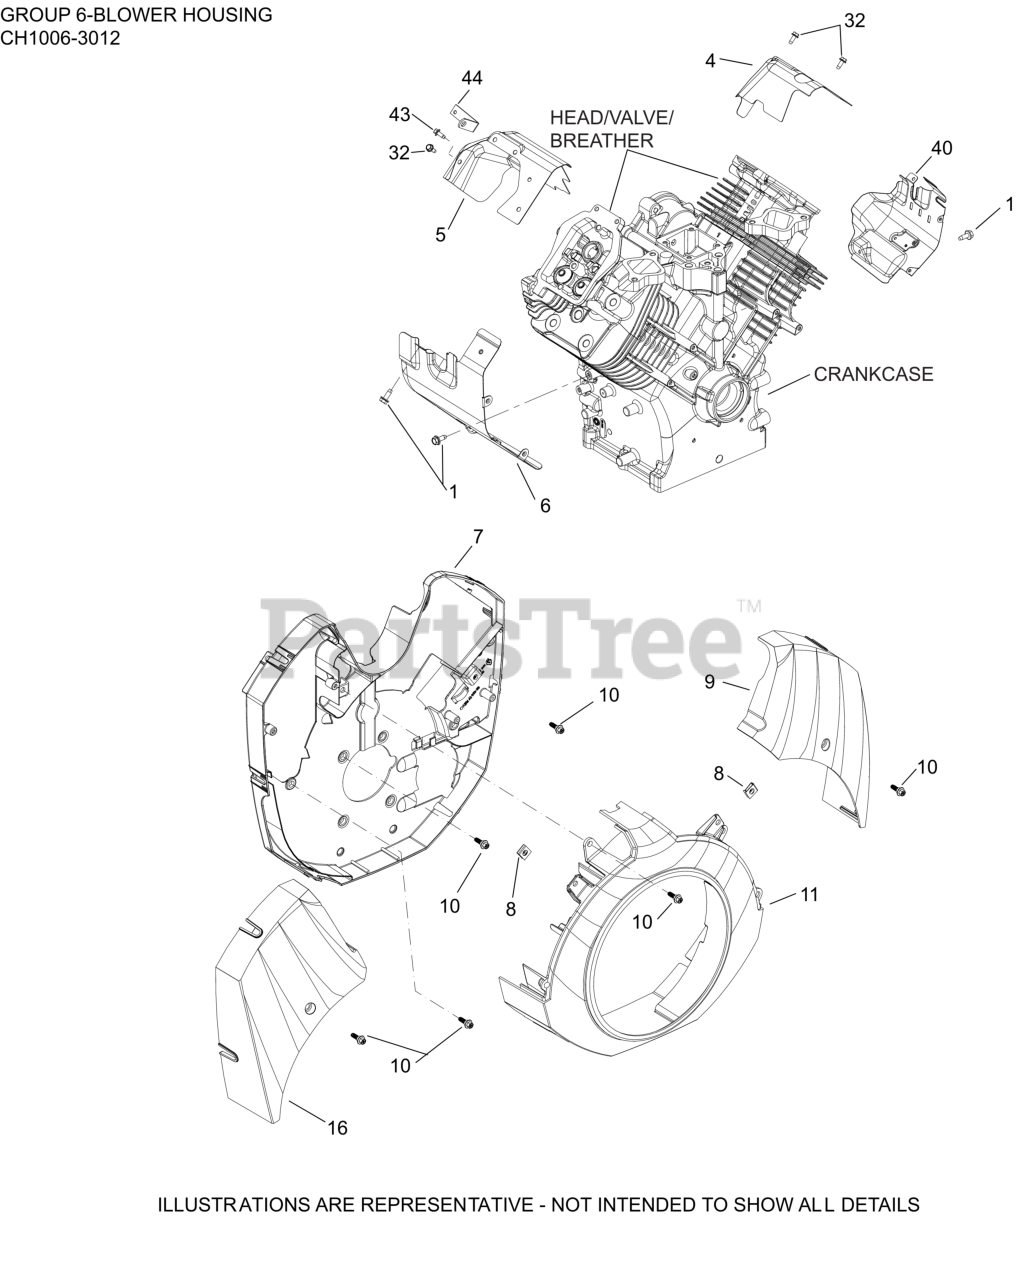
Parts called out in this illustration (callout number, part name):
1	SCREW, THREAD FORMING
4	BAFFLE, VALLEY #1 CYLINDER
5	BAFFLE, VALLEY #2 CYL-USE 62 063 40-S
6	BAFFLE, BARREL (#2 CYL)
7	SHROUD AND CLIP ASSEMBLY
8	CLIP, BAFFLE MOUNTING
9	SHROUD, #1 CYLINDER
10	SCREW, SHD THD FRM
11	KIT, BLOWER HOUSING
16	SHROUD, #2 CYLINDER
32	SCREW, FLG M6x1.0x20
40	BAFFLE, BARREL (#1 CYL)
43	SCREW, THREAD FORMING
44	STRAP, LIFTING
